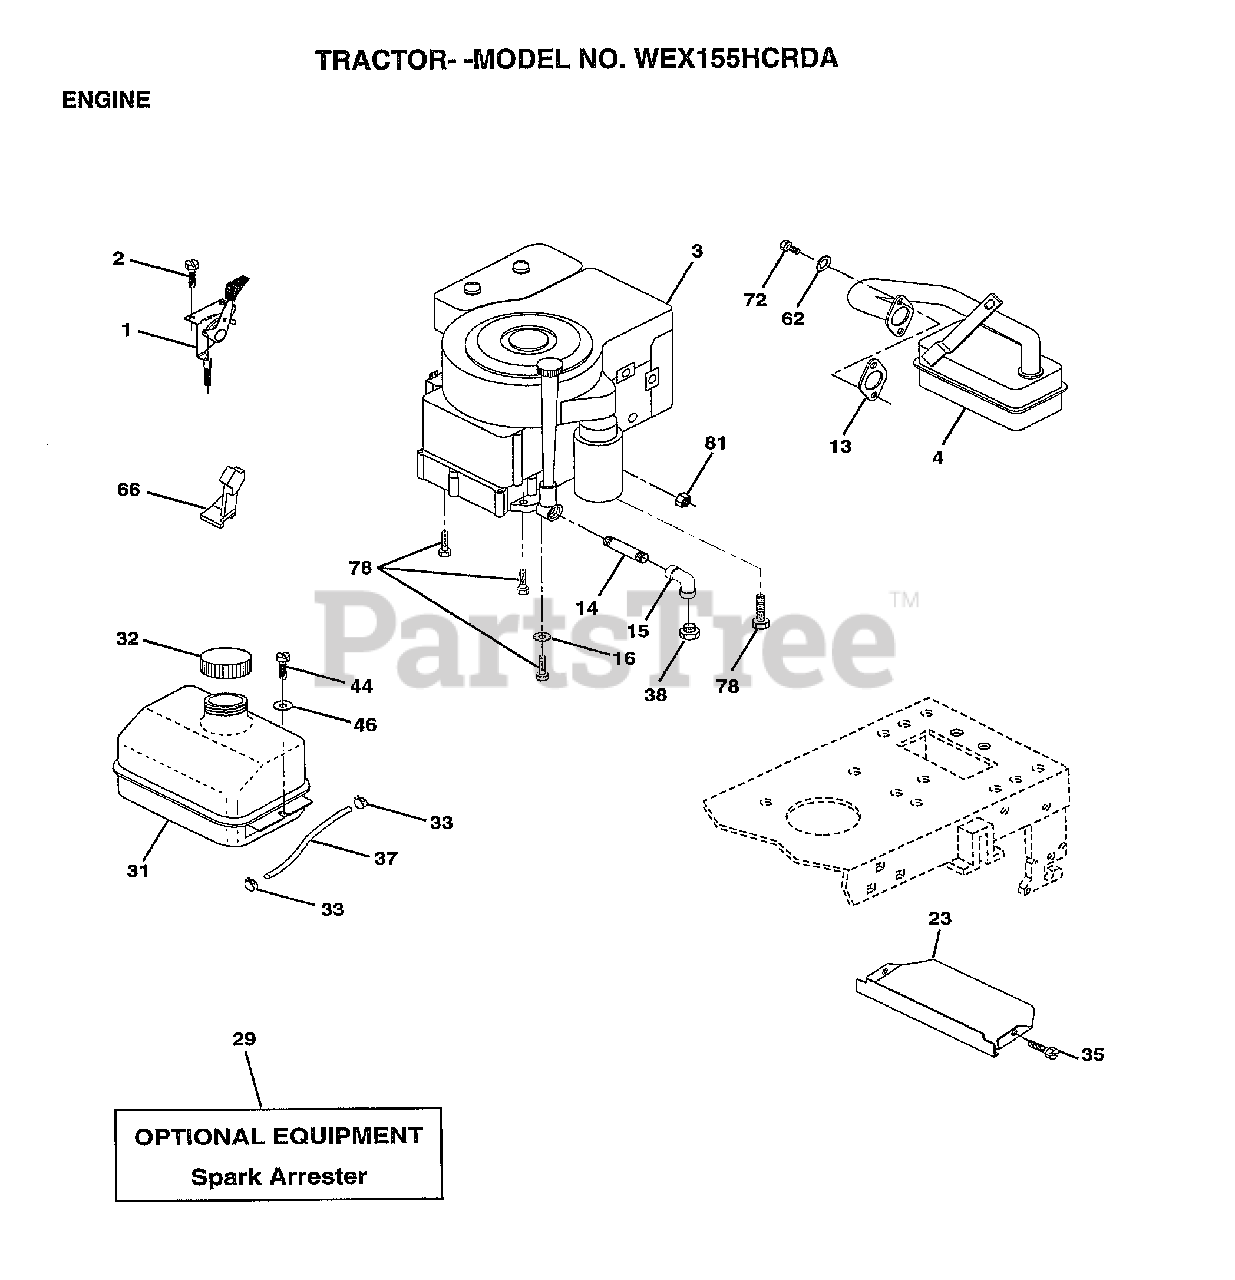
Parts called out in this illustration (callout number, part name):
1	CONTROL.THTL.23.5
2	SCREW LT
4	MUFFLER
14	PIPE NIPPLE
15	ELBOW
16	LOCKWASHER
23	SHIELD.BRN/DBR.GD
31	TANK.FUEL.LT.
32	CAP ASM FUEL
33	HOSE CLAMP
35	SCREW
37	LINE FUEL
44	SCREW HEX CRT
46	WASHER
62	LOCKWASHER
66	"STOP,DASH THROTT"
72	SCREW
78	SCREW
81	NUT
